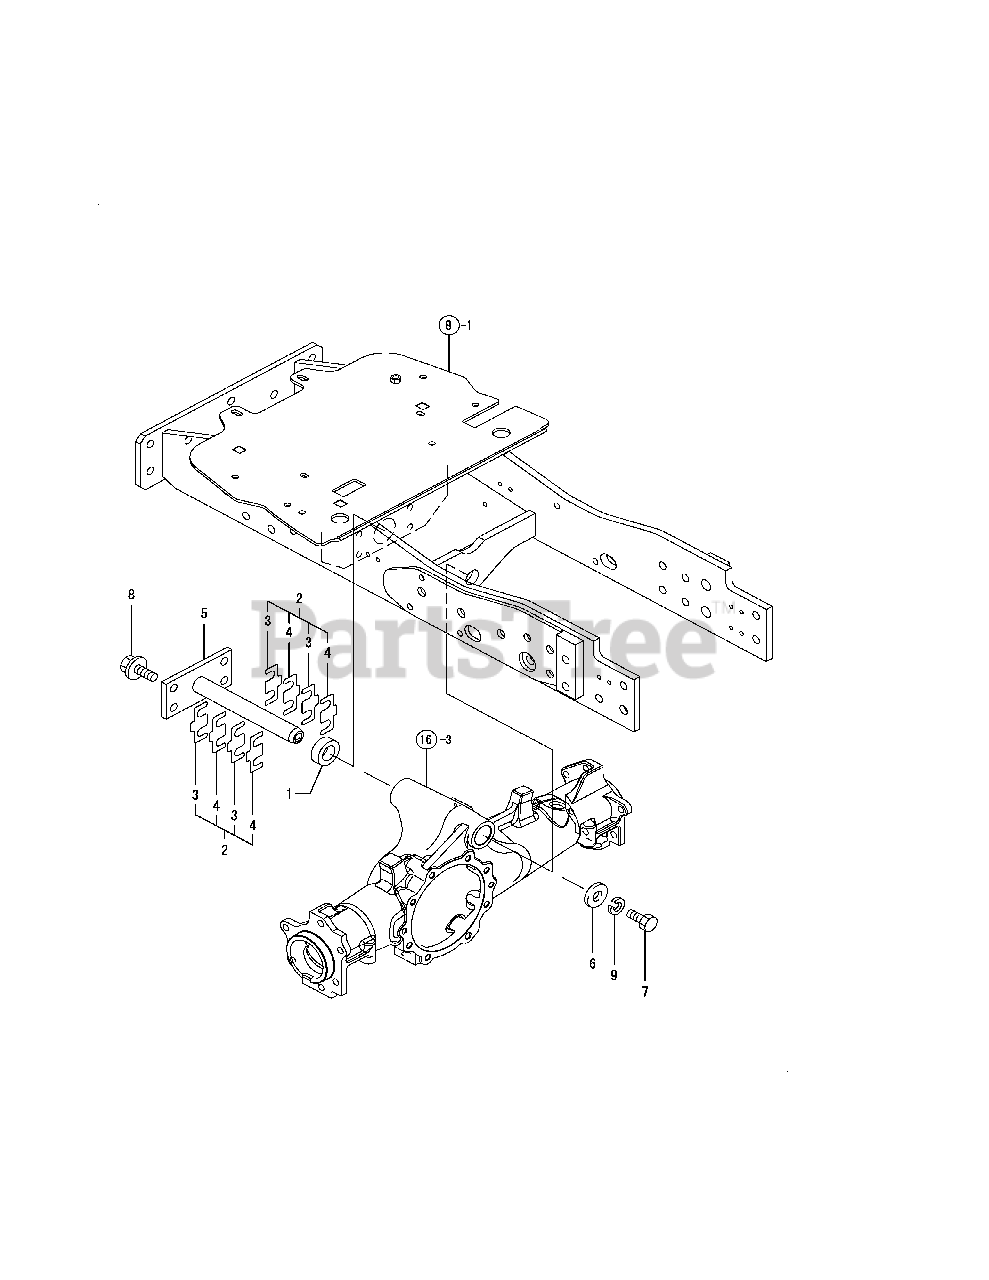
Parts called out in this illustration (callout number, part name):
1	SPACER 25X42X14
2	SHIM PIN, CENTER
7	BOLT M14X 30 PLATED
9	SPRING WASHER 14
